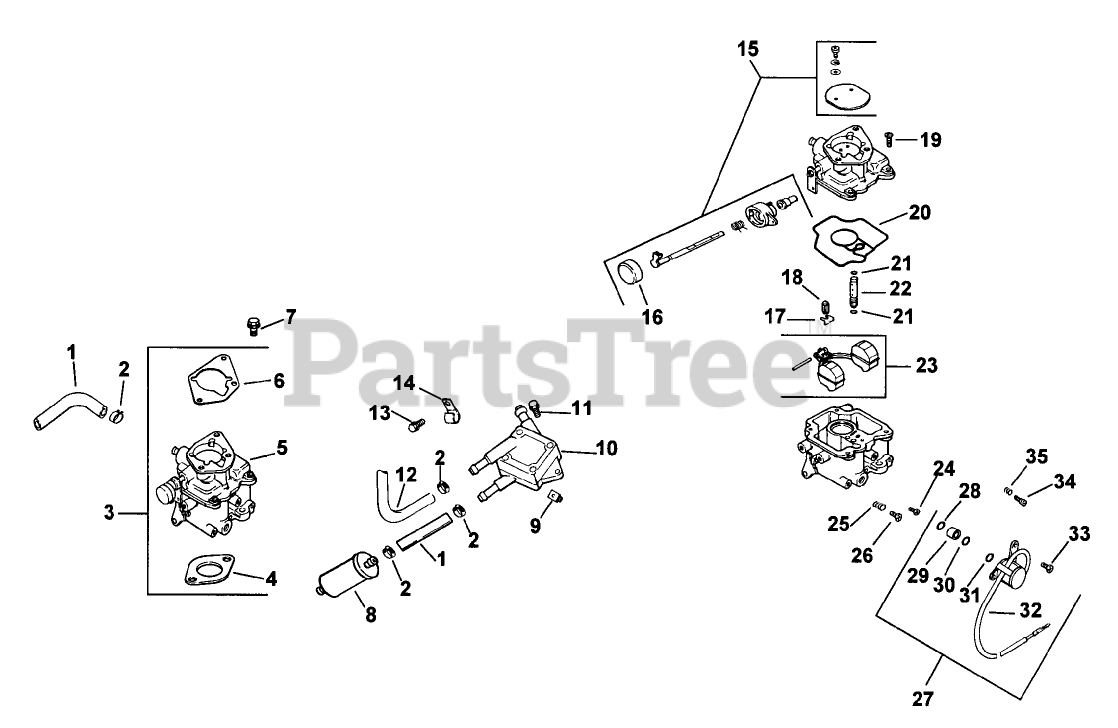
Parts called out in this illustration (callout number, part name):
1	Line fuel
2	Clamp
3	Kit, carburetor w/gasket (Incl. 4-6)
4	Gasket
5	Carburetor Asm (Incl. 11-31, carburetor repair kit 24 757 03)(For information only not available separately)
6	Gasket
7	Screw
8	Filter-Fuel
9	Nut
10	Pump-Fuel
11	Screw
12	Line, fuel 10"
13	Screw
14	Clip, cable
15	Kit, choke repair (Incl. 16)
16	Cap-Choke Lever
17	Clip, cable
18	Valve-Inlet Needle
19	Screw
20	Gasket-Body,Carburetor
21	"O"Ring
22	Jet-Slow
23	Roat Repair Kit
24	Jet-Main
25	Spring-Idle Speed Adj.
26	Screw, idle adjusting
27	Kit, solenoid (Incl. 28-33)
28	O-Ring
29	Seat-Solenoid
30	O-Ring
31	O-Ring
32	Solenoid
33	Screw
34	Needle, idle
35	Spring-Idle Adj.
